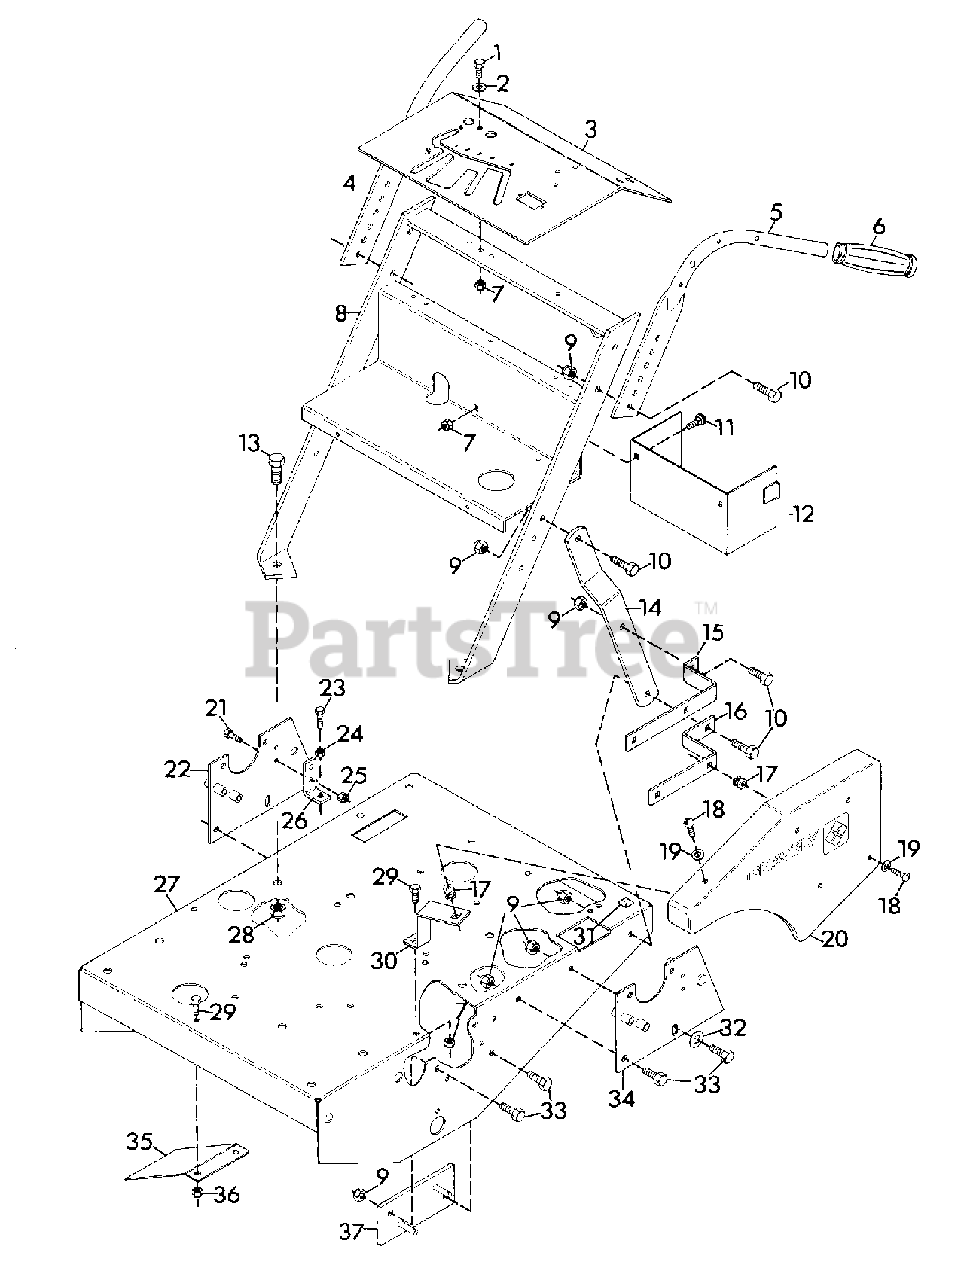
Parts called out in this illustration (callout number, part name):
1	BOLT, HEX 5/16-18X1.00
2	WASHER, FLAT .344X.688X.065
3	PLATE, SILK SCREEN
4	HANDLEBAR, R.H.
5	HANDLEBAR, L.H.
6	GRIP, HANDLEBAR
8	WELDMENT, HANDLEBAR SUPPORT
9	NUT, LOCK 3/8-16
10	BOLT, HEX 3/8-16X1.25
13	BOLT, HEX 1/2-13X1.25
14	BRACE, HANDLEBAR SUPPORT
15	BRACKET, TOP
16	BRACKET, BOTTOM
17	GROMMET, PLASTIC
18	SCREW, MACHINE 1/4-20X.625 RD HD
19	WASHER, FLAT .281X.625X.065
20	GUARD, BELT L.H.
20	GUARD, BELT R.H.
21	BOLT, HEX 1/4-20X.625
22	WELDMENT, BEARING SUPPORT R.H.
23	BOLT, HEX 1/4-20X1.00
24	NUT, HEX 1/4-20
25	NUT, LOCK 1/4-20
26	BRACKET
27	FRAME, PRO
28	NUT, LOCK 1/2-13
30	SUPPORT, FRONT L.H.
30	SUPPORT, FRONT R.H.
31	STOP
32	WASHER, FLAT .406X.812X.065
33	BOLT, HEX 3/8-16X1.00
34	WELDMENT, BEARING SUPPORT L.H.
37	WELDMENT, BRAKE PIN PLATE L.H.
37	WELDMENT, BRAKE PIN PLATE R.H.
NS	DECAL, AMERICA
